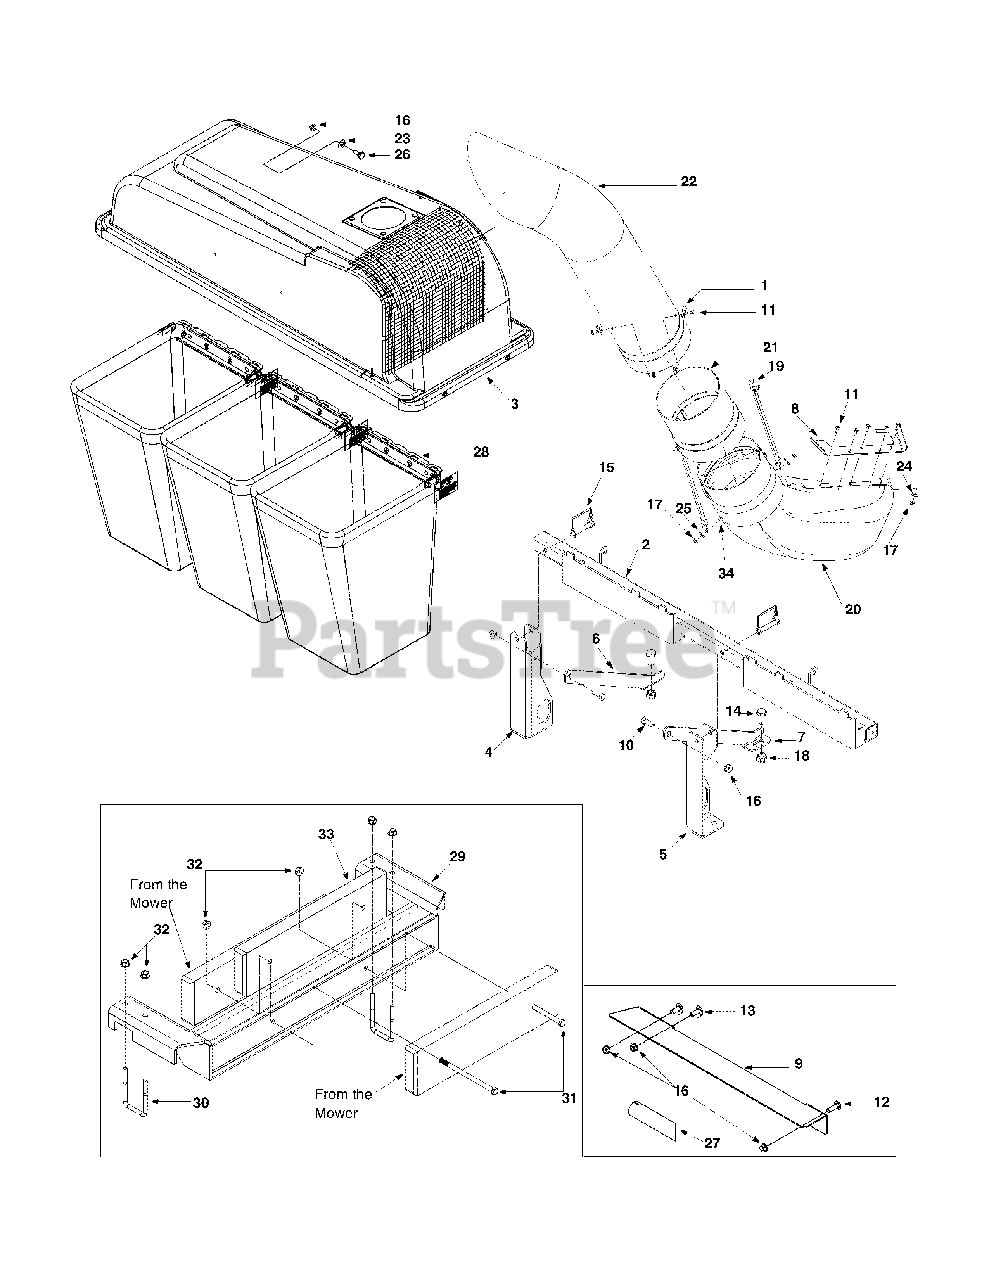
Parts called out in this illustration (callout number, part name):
1	Retainer Hook
2	Catcher Support Bracket
3	Catcher Cover
4	Upright Mounting Bracket LH
5	Upright Mounting Bracket RH
6	Upright Gusset LH
7	Upright Gusset RH
9	Baffle Bracket
10	Hex Bolt 3/8-16 x 1.0"
11	Hex Bolt 1/4-20 x 0.620"
12	Carriage Bolt 3/8-16 x 1.25"
13	Carriage Bolt 3/8-16 x 1.0"
14	Hex Bolt 1/2-13 x 1.0"
16	Top Lock Flange Nut 3/8-16
17	Flange Lock Nut 1/4-20
18	Lock Nut 1/2-13
19	Chute Strap
20	Chute Elbow
21	Extension Tube
22	Chute Tube
23	Beleville Washer
24	Bell Washer
25	Flat Washer
26	Shoulder Screw 3/8-16
27	Exhaust Pipe: Kawasaki
28	Grass Bag
29	Weight Bar Bracket
30	U Bolt 3/8-16 x 1.5"
31	Hex Bolt 3/8-16 x 6.25"
32	Top Lock Flange Nut
34	Hex Bolt 1/4-20 x 1"
